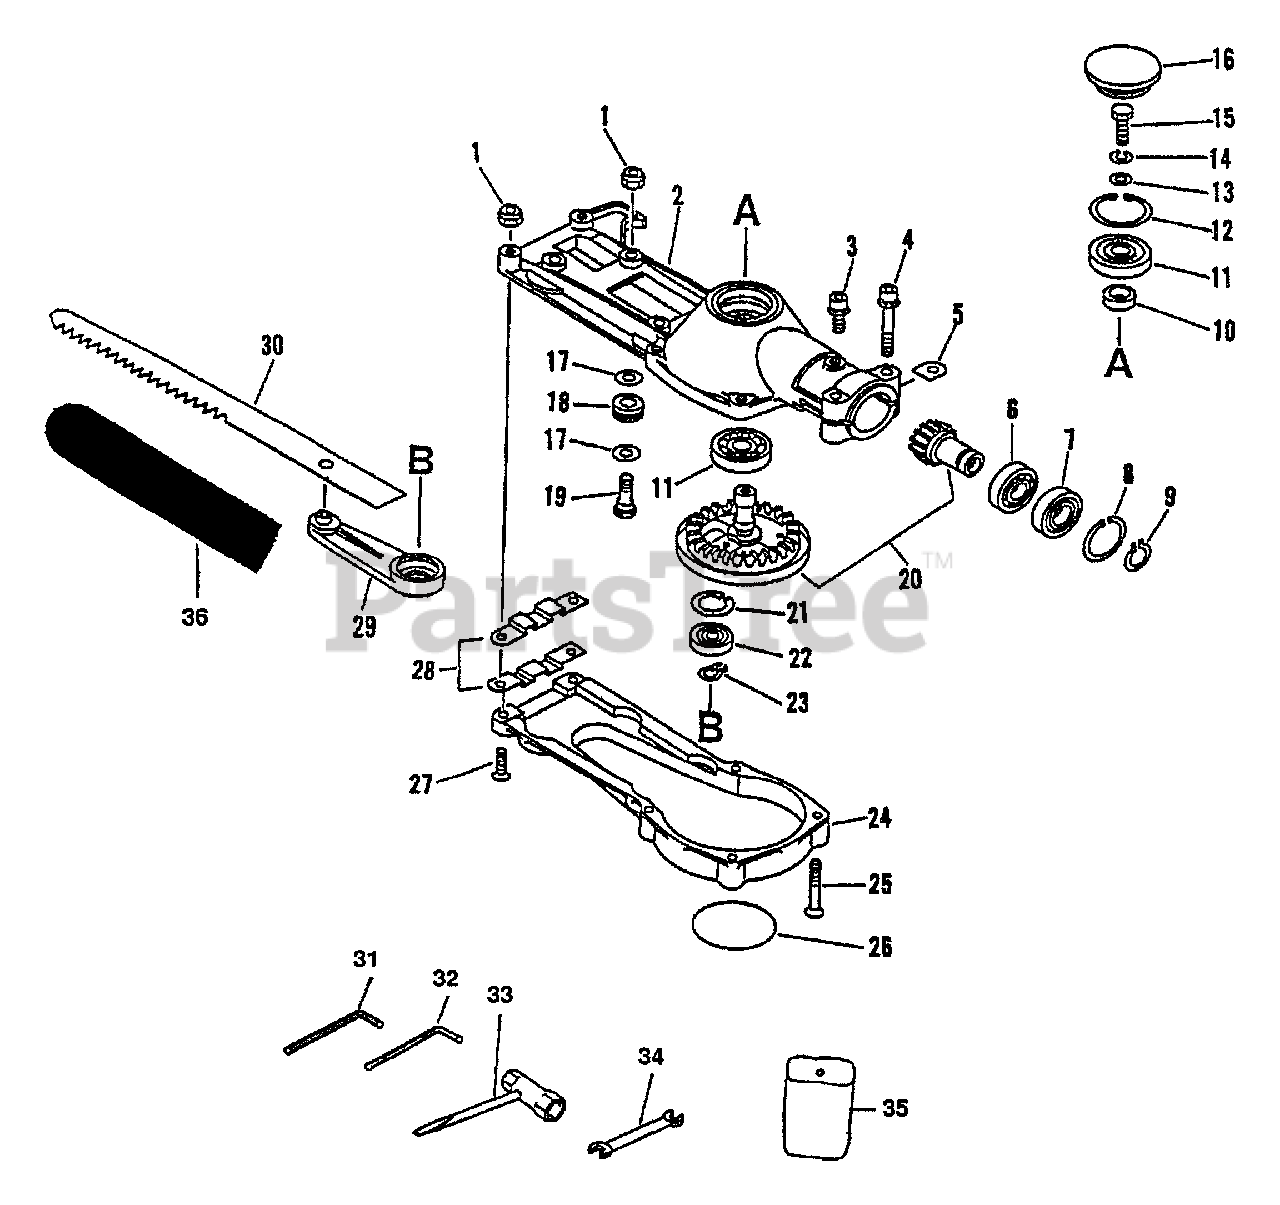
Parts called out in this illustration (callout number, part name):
2	CASE, GEAR
3	SCREW - 5X12
4	SCREW - 5X28
6	BEARING, BALL - 6901
7	BEARING, BALL - 6901Z
8	RING, RETAINING - 24
9	RING, RETAINING - 12
11	BEARING, BALL - 6000Z
12	RING, RETAINING - 26
13	WASHER - 5
14	LOCKWASHER - 5
15	BOLT - 5X16
16	LID, GEAR CASE
18	SUPPORT, BLADE
19	BOLT - 6
20	GEAR SET
21	RING, RETAINING - 19
22	BEARING, BALL - 607
23	RING, RETAINING - 7
24	LID, GEAR CASE
25	BOLT - 5X30
26	LABEL - ECHO
27	BOLT - 5X18
28	SUPPORT, BLADE
29	CONNECTING ROD ASSY
30	GUIDE, BLADE
31	HEX KEY - 4mm
32	HEX KEY - 3mm
33	T-WRENCH - 17X19mm
34	SPANNER - 8X10mm
35	BAG, TOOL
36	COVER, BLADE
